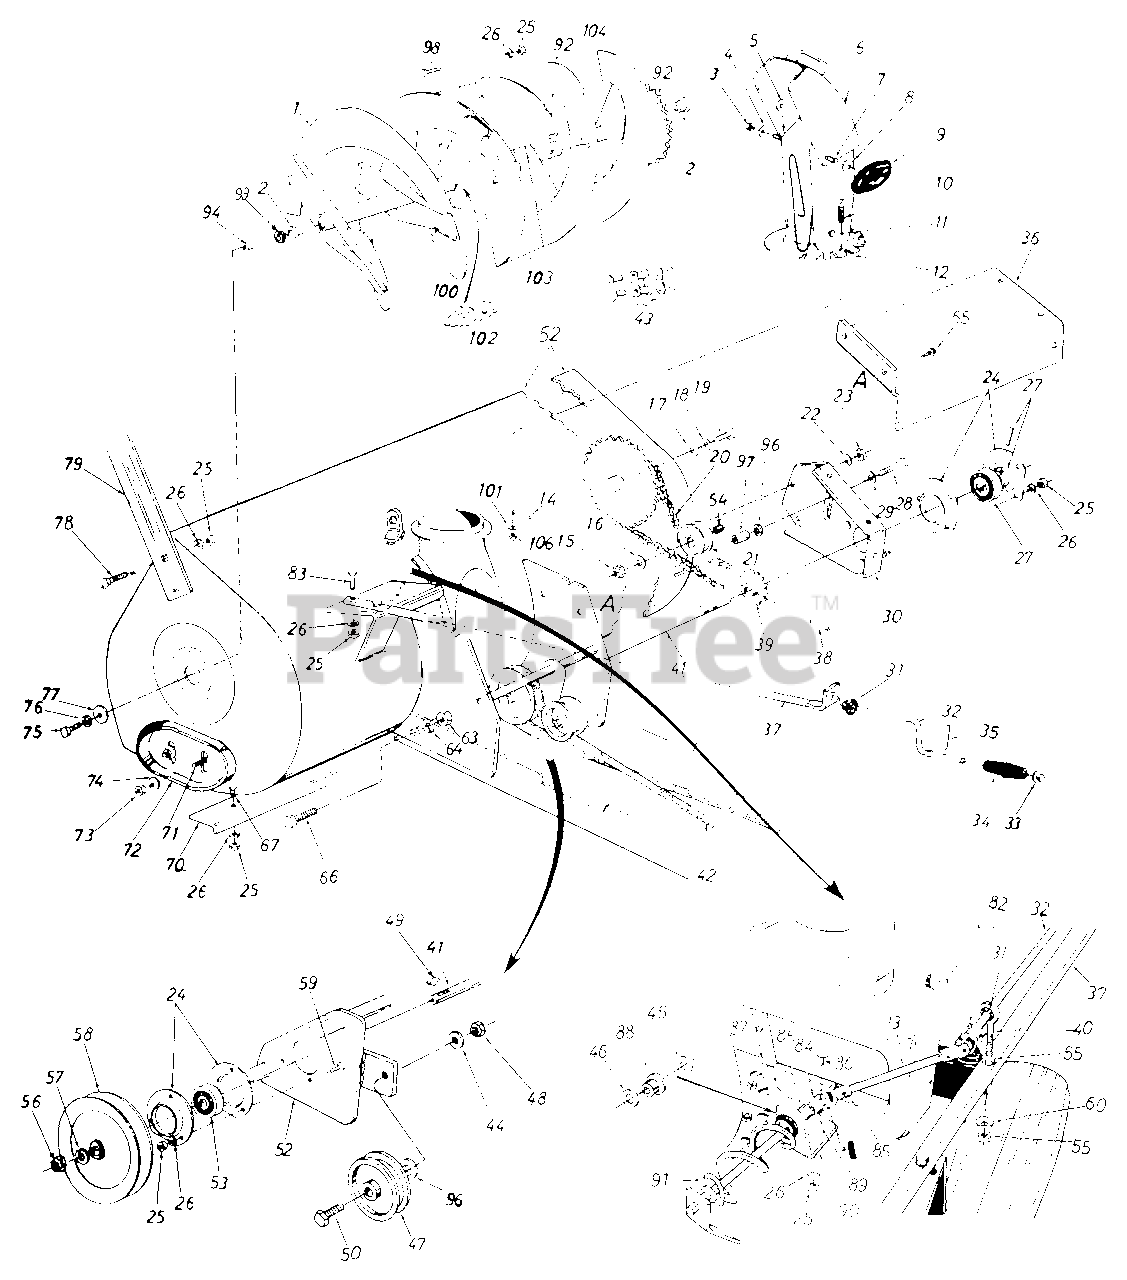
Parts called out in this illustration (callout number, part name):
1	Spirai Ass'y. (L.H.)
2	Flange Bearing
3	Hex Cent. L.-Nut 5/16-18 Thd.
4	Belleville Wash. 3/8" I.D.
5	Flat Washer 3/8" I.D.
6	Top Chute Ass'y.
7	Carriage Bolt 5/16-18 x .62"-Lg.*
8	Belleville Washs. 3/8" I.D.
9	Hand Knob
10	Truss Mach Scr. 1/4-20 x .75"-Lg.
11	Push Cap .188" Dia. Rod
12	Chute Ass'y.
13	Chute Crank Extension Rod
14	Chute Flange Keeper
15	L.-Nut 3/8-16 Thd.
16	Fl.-Wash.
17	Fl.-Wash.
18	Belleville Wash.
19	Hex Bolt 1/2-13 x 1.00" Lg.*
20	#420 Chain 1/2" Pitch x 77 Links
21	Plastic Idler 2.00" O.D.
22	L.-Wash. 1/4" I.D.*
23	Hex Nut 1/4-20 Thd.*
24	Bearing Housing
25	Hex Nut 5/16-18 Thd.*
26	L.-Wash. 5/16" I.D.*
27	Self-Aligning Bearing
28	Hex Bolt 3/8-16 x 175" Lg *
29	Belleville Wash. 3/8" I.D.
30	Chain Guard Ass'y.
31	Nylon Bushing
32	Chute Crank .375 Dia. x 33"-Lg.
33	Push Nut 3/8" Rod
34	Knob (Black)
35	Roll Pin
36	Drive Shaft Cover
39	14 Teeth Sprocket Ass'y.
40	Eyebolt 5/16-18 x 3.0" Lg.
41	Drive Shaft
42	VBelt 1/2" x 88" Lg. Kevlar
43	Master Link for #420 Chain
44	L.-Wash. 3/8" I.D.*
45	Fl.-Wash. .385 I.D. x .62" O.D.
46	Fl.-Wash. .390 I.D. x 1.50" O.D.
47	Fl.-ldler with Flanges
48	Hex Jam L.-Nut 3/8-26 Thd.
49	#61 Hi-Pro Key
50	Hex Bolt 3/8-16 x 1.50" Lg.*
52	Spiral Housing Ass'y.
53	Self-Aligning Bearing
54	Sleeve Bearing .50" I.D.
55	Hex Nut 5/16-18 Thd.*
56	Hex Nut 3/4-10 Thd.
57	L.-Wash. 3/4" I.D.
58	VPulley .750" I.D. x 6.00" O.D.
59	Hex Sems Bolt 5/16-18 x .75" Lg.*
60	Bell.-Wash. .345" I.D. x .88" O.D.
63	Hex L.-Nut 1/2-20 Thd.
64	L.-Wash. 1/2"I.D.*
65	Hex Wash. Hd. Tap Scr. 1/4-20 x .50" Lg.
66	Hex Bolt 1i2-20 x 1.25" Lg.*
67	Carriage Bolt 5/16-18 x .62"*
72	Skid Shoe
73	Hex Nut 3/8-16 Thd.*
74	Belleville Wash. 3/8" I.D.
75	Hex Bolt 1/2-13 x 1.00" 4.*
76	Belleville Wash. 1/2" I.D.
77	Fl.-Wash.
78	Carriage Bolt 5/16-18 x .62" Lg.*
79	Drift Cutter
82	Cotter Pin
83	Hex Bolt 5/16-18 x 1.50" Lg.*
84	Joint Block
85	Joint Bracket Ass'y.
86	Oval Head Rivet
87	Spring Pin Roll 1/8" Dia. x .75" Lg.*
88	Nylon Bushing
89	Carriage Bolt 5/16-18 x .62
90	Chute Crank Bracket
91	Chute Crank Ass'y.
92	Spiral Ass'y. (R.H.)
94	Spiral Axle
96	Flat Washer
97	Idler Spacer
98	Carriage Bolt 5/16-18 x .75" Lg.
99	Fl.-Wash. 1.0" I.D. x 1.75" O.D.
100	Fl.-Wash. 1.03" I.D. x 1.62" O.D.
101	Bell. Wash. 1/4" I.D.
102	Plastic Bushing
103	Rotor Paddel Ass'y.
104	Spring Pin Spir. 5/16" Dia. x 1.75" Lg.
106	Hex Nut 1/4-20 Thd.
